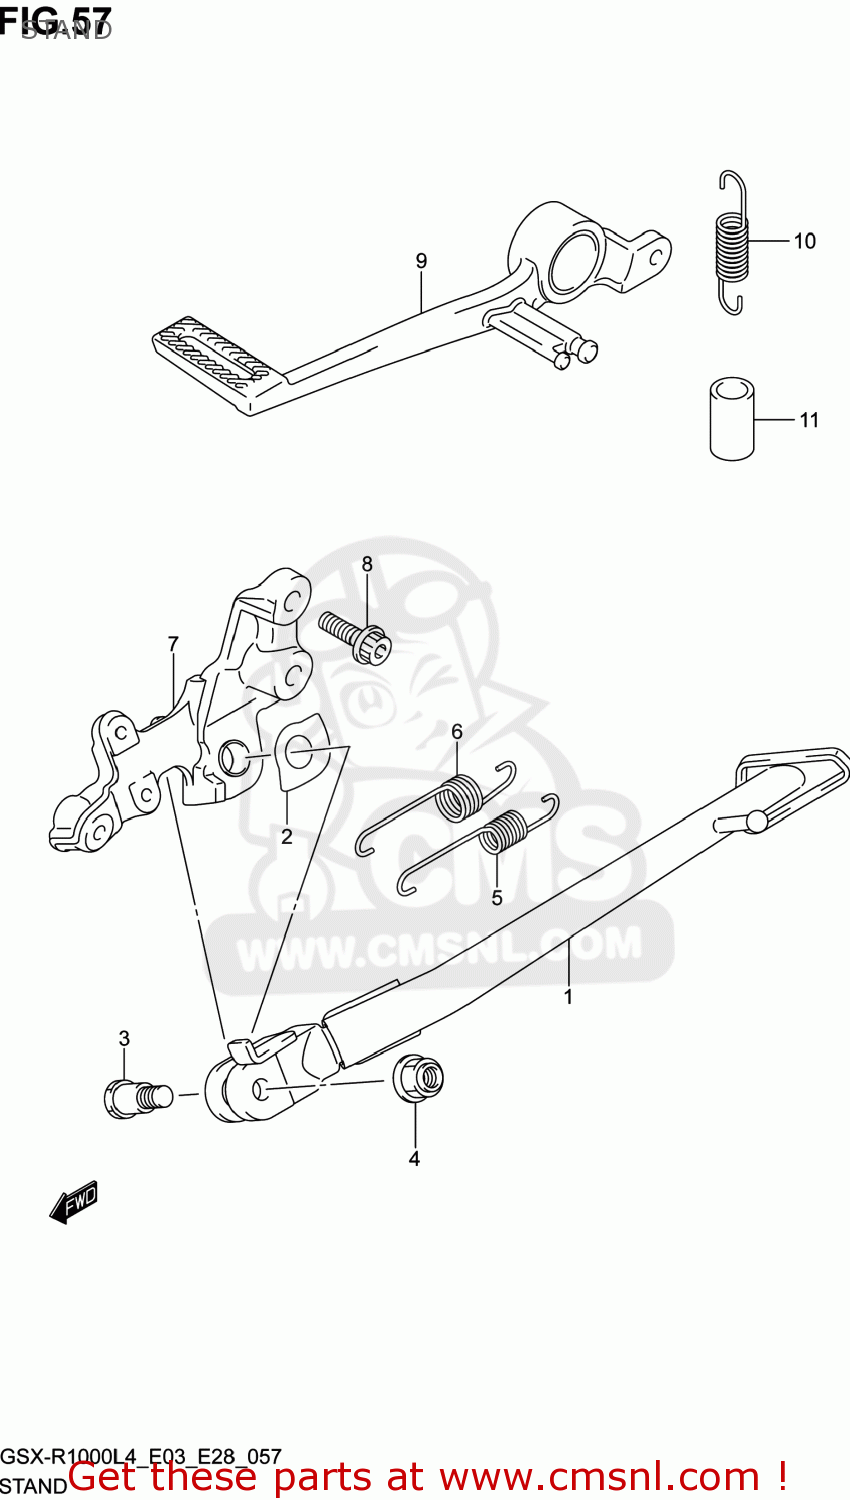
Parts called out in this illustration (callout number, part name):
1	STAND,PROP
2	WASHER,PROP STAND
3	BOLT,PROP STAND
4	NUT
5	SPRING
6	SPRING
7	BRACKET,PROP STAND
8	BOLT(10X28)
9	PEDAL,BRAKE
10	SPRING
11	HOSE(11X15X600)
